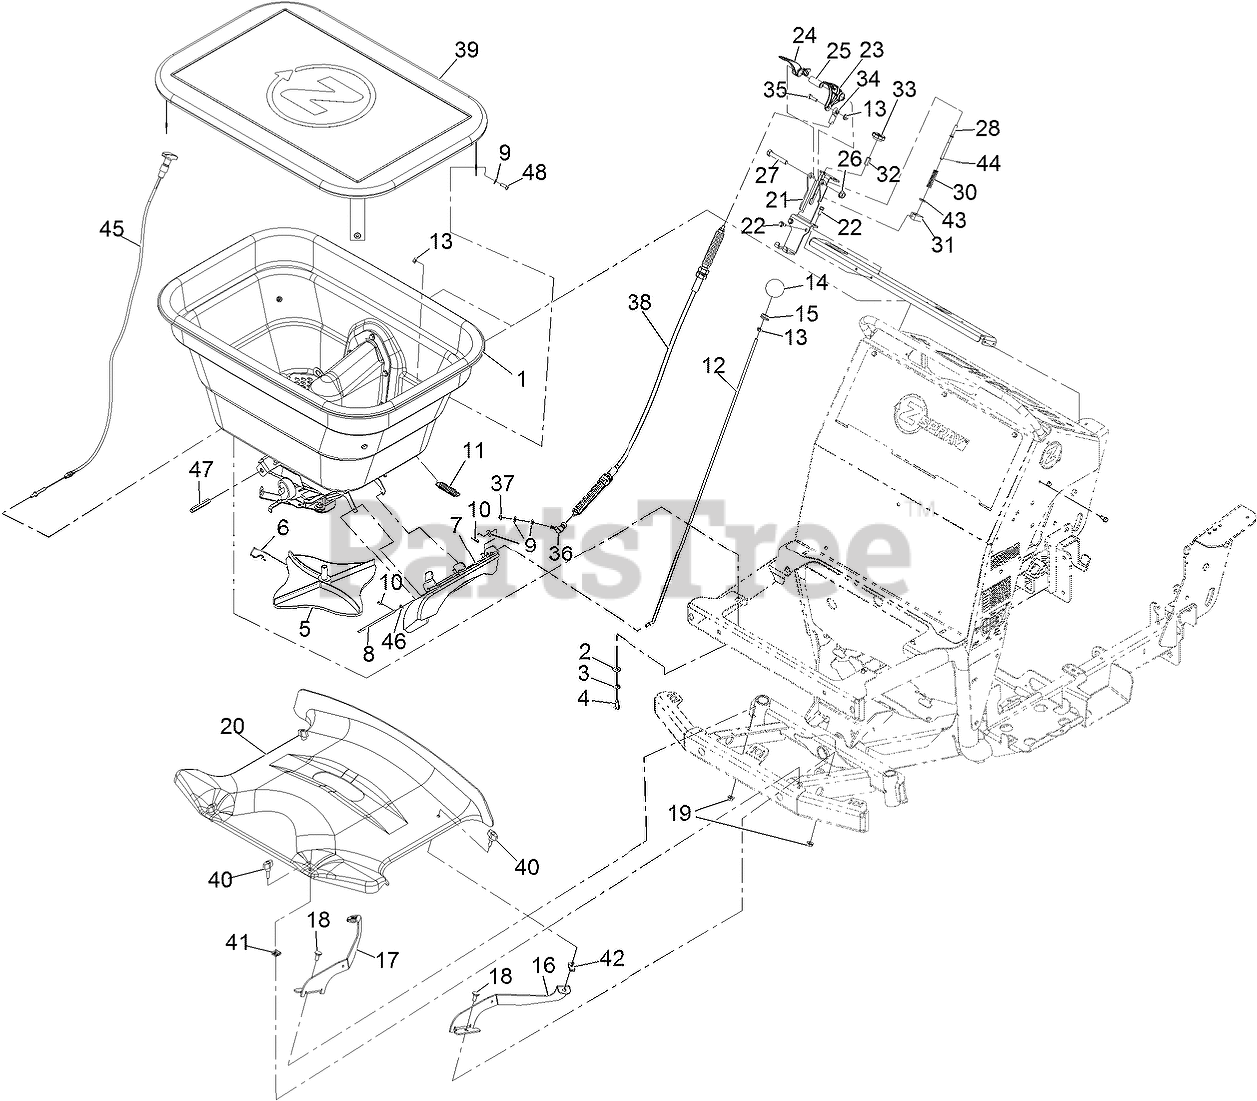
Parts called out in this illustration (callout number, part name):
1	Spreader Hopper ASM
3	WASHER-LOCK
4	SCREW-HH
5	SPINNER-SPREADER
6	CLIP-SPINNER
7	Side Deflector ASM
8	PIN-DEFLECTOR SS
9	WASHER-FLAT
10	PIN-COTTER, HAIR
11	SPRING-EXTENSION
12	ROD-CONTROL, DEFLECTOR
14	KNOB-RATE, FLOW
15	GROMMET
16	BRACKET-COVER, FRONT (LH)
17	BRACKET-COVER, FRONT (RH)
18	SCREW-CARR
20	COVER-FRONT, SPREADER/SPR
21	MOUNT-HANDLE
22	SCREW-HWH
23	LEVER-SPREAD, WIDE
24	LEVER-SPREAD, NARROW
27	SCREW-HH
28	LINK-ADJUST, NARROW
30	SPRING-COMPRESSION, BAIL
31	STOP-SPREAD, NARROW
32	NUT-COUPLER
34	ROD END-BALL JOINT
35	SCREW-HH
36	BALL-JOINT
37	NUT-HEX, NI
39	Cover-Hopper, Clear Vinyl Window
41	NUT-RETAINER, U STYLE
42	NUT-RETAINER
43	WASHER-FLAT
44	PIN-COTTER
45	CABLE-CONTROL, TURN LOCK
46	WASHER-FLAT
47	POST-HEX, DIFFUSER GUIDE
48	SCREW-HH
